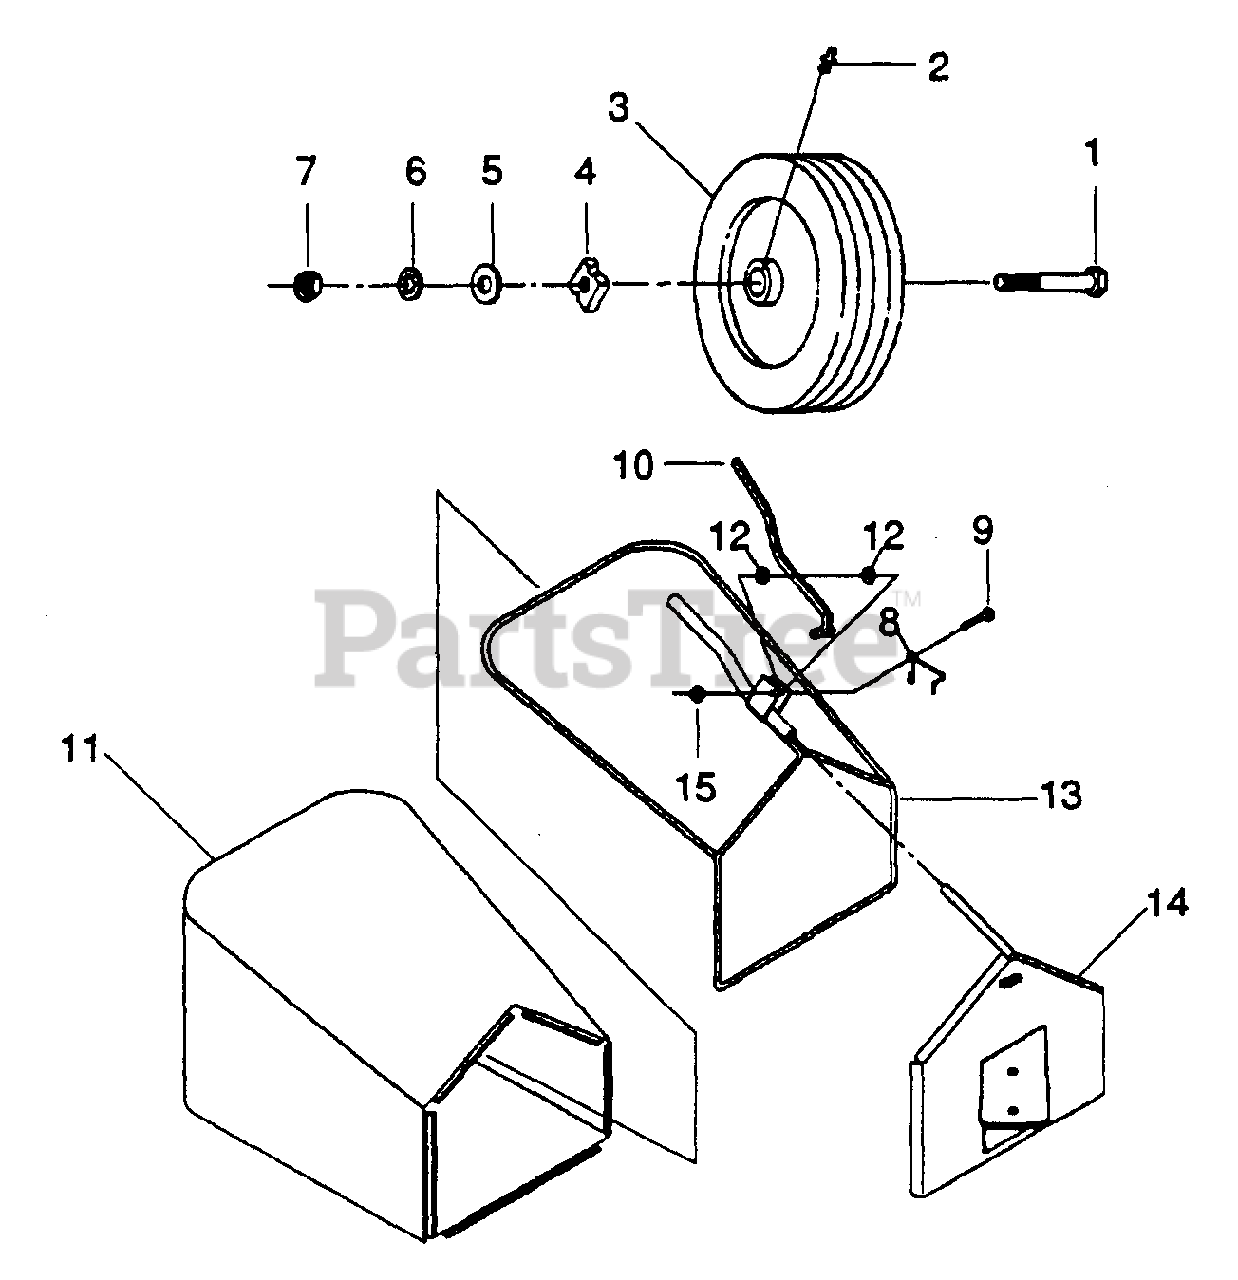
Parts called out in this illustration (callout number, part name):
1	BOLT - 1/2-13 X 3-1/2"
2	FITTING, GREASE
3	WHEEL, BEARING - FRONT -- 8"
3	WHEEL, BEARING - REAR -- 10"
4	AXLE WHEEL NUT
5	WHEEL WASHER
6	LOCKWASHER
7	NUT - 1/2-13
7	GRASS CATCHER KIT
8	CATCHER, LATCH SPRING
9	1/4-20 X 1-1/2" HEX HD.
10	CATCHER, LATCH
11	BAG, DEBRIS
12	HANDLE WASHER
13	CATCHER, FRAME
14	PLATE, PREVENT
15	NUT - 1/4"
